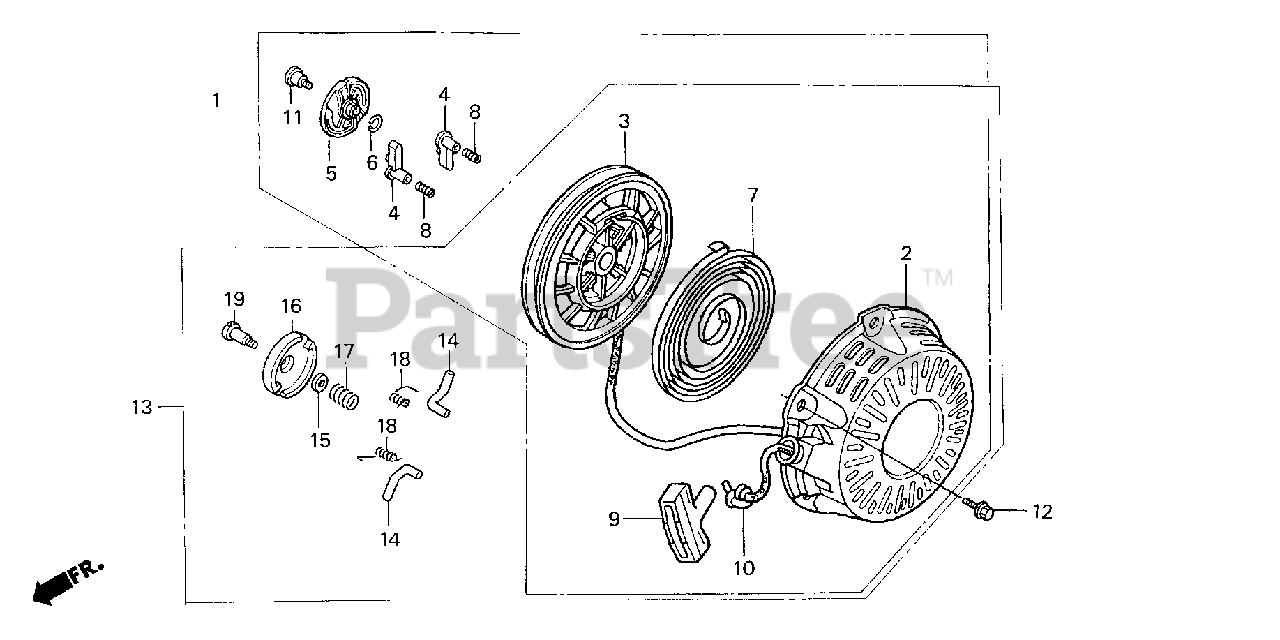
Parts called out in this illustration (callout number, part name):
1	STARTER ASSY., RECOIL *R280* (POWER RED)
2	CASE, RECOIL STARTER *R8* (BRIGHT RED)
2	CASE, RECOIL STARTER *R280* (POWER RED)
3	REEL, RECOIL STARTER (NATURAL)
4	RATCHET, STARTER
5	GUIDE, RATCHET
6	SPRING, FRICTION
7	SPRING, RECOIL STARTER
8	SPRING, RETURN
9	KNOB, RECOIL STARTER
10	ROPE, RECOIL STARTER
11	SCREW, SETTING
12	BOLT, FLANGE (6X8)
